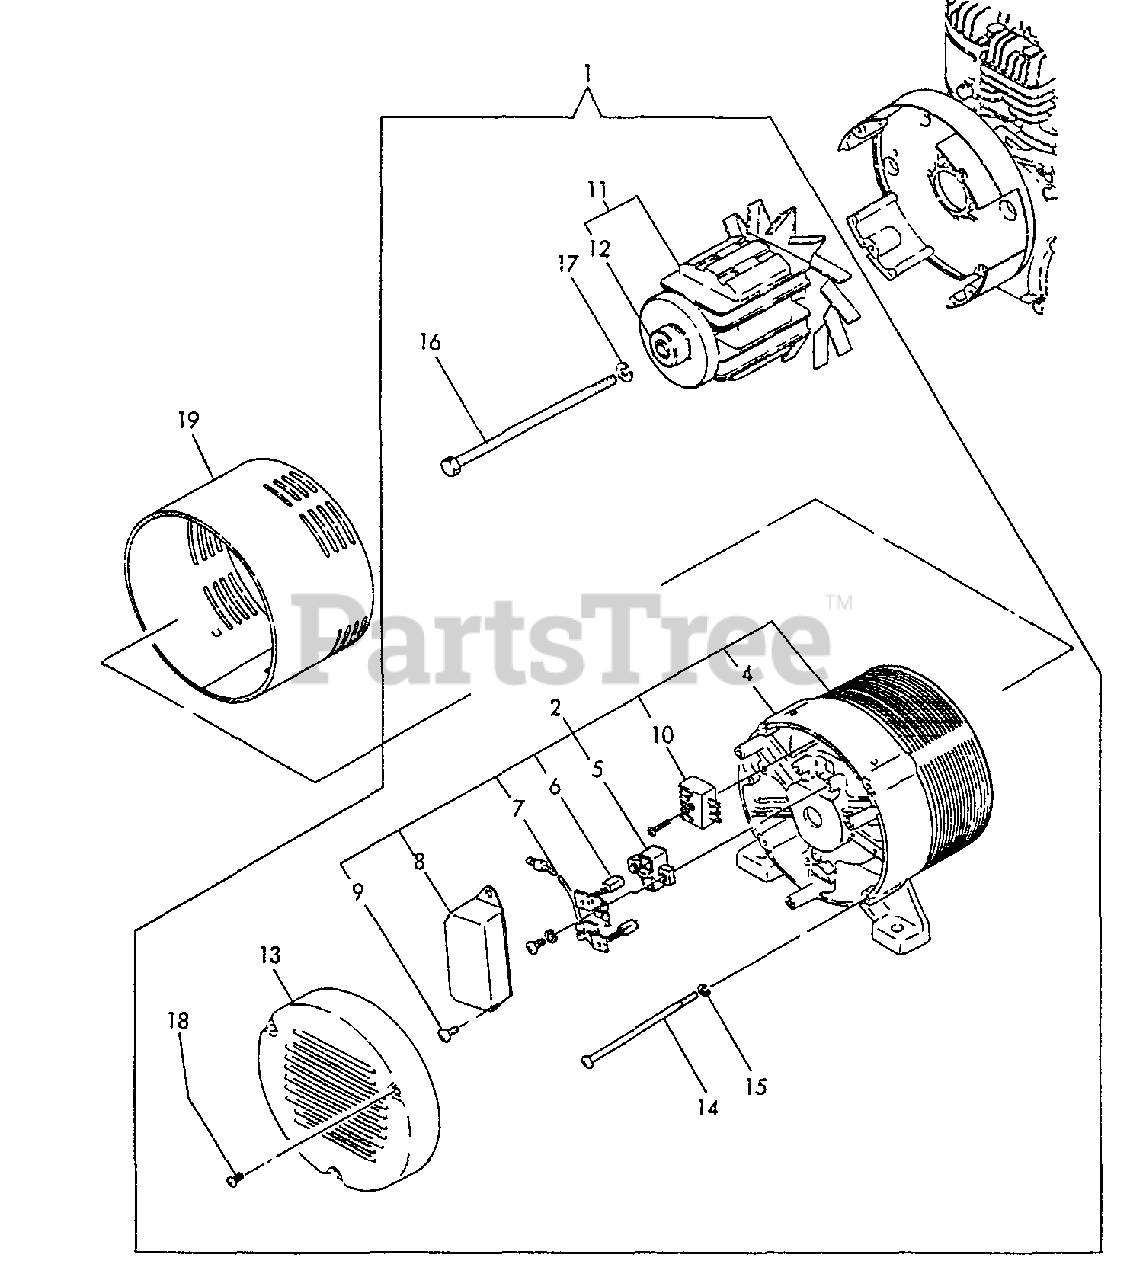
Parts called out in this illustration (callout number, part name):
1	GENERATOR 2.0 KVA
2	STATOR ASSY
4	COVER - REAR
5	HOLDER, BRUSH
6	BRUSH - ( + )
7	BRUSH - ( - )
8	A.V.R.
9	SCREW - 5X14
10	RECTIFIER
11	ROTOR ASSY
12	BEARING, BALL
13	COVER
14	BOLT, THROUGH
15	LOCKWASHER - 6
16	BOLT
17	LOCKWASHER - 8
18	SCREW - 4X8
19	BAND
